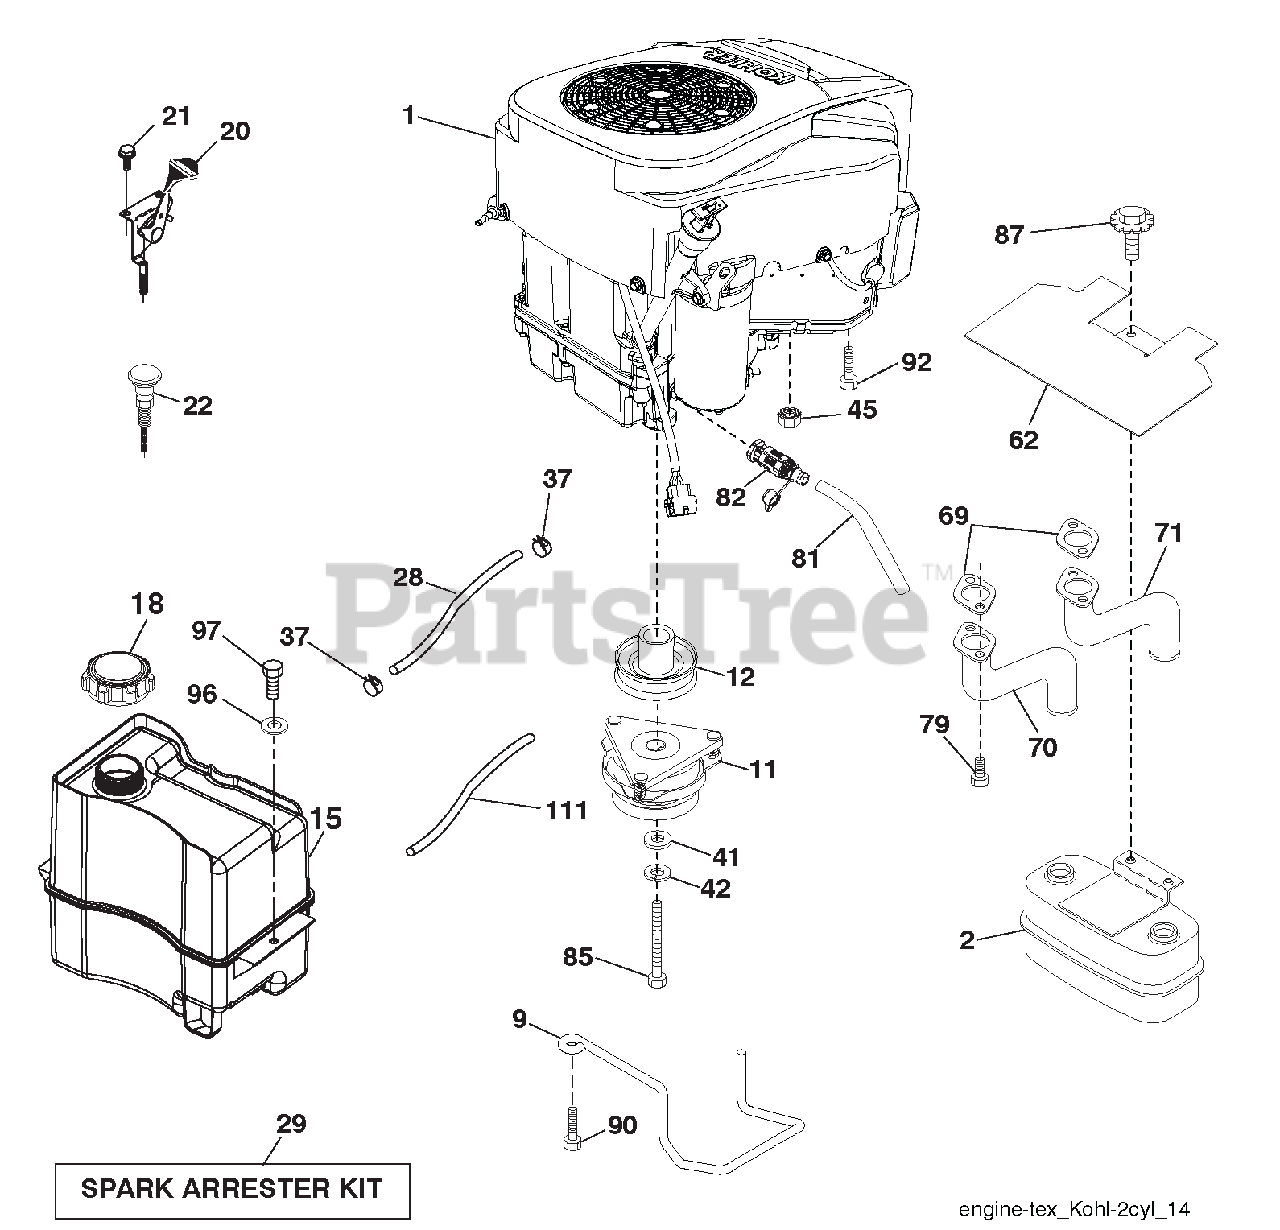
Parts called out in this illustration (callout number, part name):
1	KOHLER.ENGINE
2	MUFFLER ASM.TWIN.LO-TONE
9	KEEPER.BELT.ENGINE.4.25"NSTG
11	CLUTCH OGURA
12	PULLEY.ENGINE.TUFFTORQE.1"CRK.
15	TANK.FUEL.2.5.GAL.
18	CAP FUEL
20	CONTROL.THROTTLE
22	CONTROL CHOKE
28	LINE.FUEL.20"
29	KIT.SPARK ARRESTOR(392390 B&S)
37	CLAMP.HOSE.BLK.
41	WASHER.1-1/2 ODX15/32 IDX.250
42	WASHER.LOCK.HVY HLCL.SPR.7/16
45	Nut, Keps Hex 1/4-20 unc
62	SHIELD.HEAT.MUFFLER.
70	PIPE.EXHAUST.LH.CV18/20
71	PIPE.EXHAUST.RH.CV18/20
79	SCREW.SOCKET HD.5/16-18 X .75
81	TUBE.DRAIN.OIL.EASY
82	VALVE OIL DRAIN
85	BOLT.HEX.7/16-20X4XGR5-1.5THR.
87	BOLT.5/16-18UNCX3/4 W/SEMS.BLK
90	SCREW.3/8-16X1.SMGML.TAP/R.BLK
92	SCREW.3/8-16 X 1.SMGML.TAP/R
96	WASHER.9/32 X 7/8 X 16GA.
97	SCREW.HEXWSH.THDROL.1/4-20X3/4
111	PURGE.LINE.CARB
